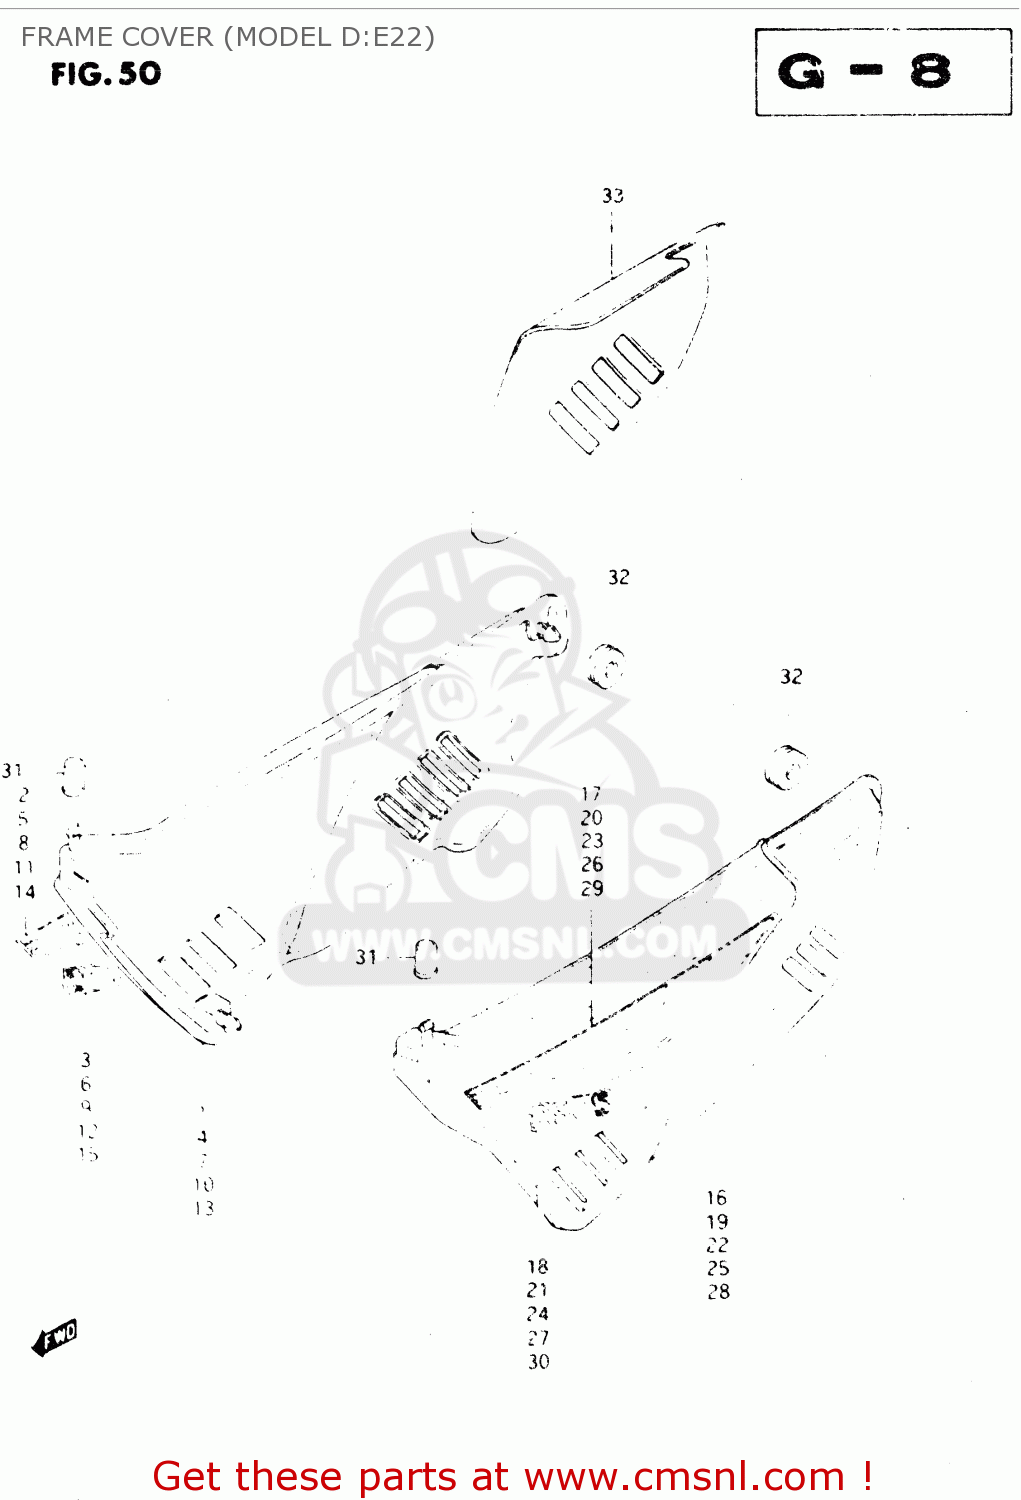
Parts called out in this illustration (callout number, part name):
1	COVER, FRAME RH (BLACK)
2	TAPE SET, FRAME COVER RH
3	EMBLEM, LH
4	COVER, FRAME RH (BLUE)
5	TAPE SET, FRAME COVER RH
6	EMBLEM, LH
7	COVER, FRAME RH (RED)
8	TAPE SET, FRAME COVER RH
9	EMBLEM, LH
10	COVER,FRAME,RIGHT
11	TAPE,FRAME COVER,RIGHT
12	EMBLEM
13	COVER, FRAME RH (YELLOW)
14	TAPE SET, FRAME COVER RH
15	EMBLEM
16	COVER, FRAME LH (BLACK)
17	TAPE SET, FRAME COVER LH
18	EMBLEM, LH
19	COVER, FRAME LH (BLUE)
20	TAPE SET, FRAME COVER LH
21	EMBLEM, LH
22	COVER, FRAME LH (RED)
23	TAPE SET, FRAME COVER LH
24	EMBLEM, LH
25	COVER, FRAME, LH
26	TAPE,FRAME COVER,LEFT
27	EMBLEM
28	COVER, FRAME LH (YELLOW)
29	TAPE SET, FRAME COVER LH
30	EMBLEM
31	CUSHION
32	CUSHION
33	HEAT SHIELD,FRAME COVER
